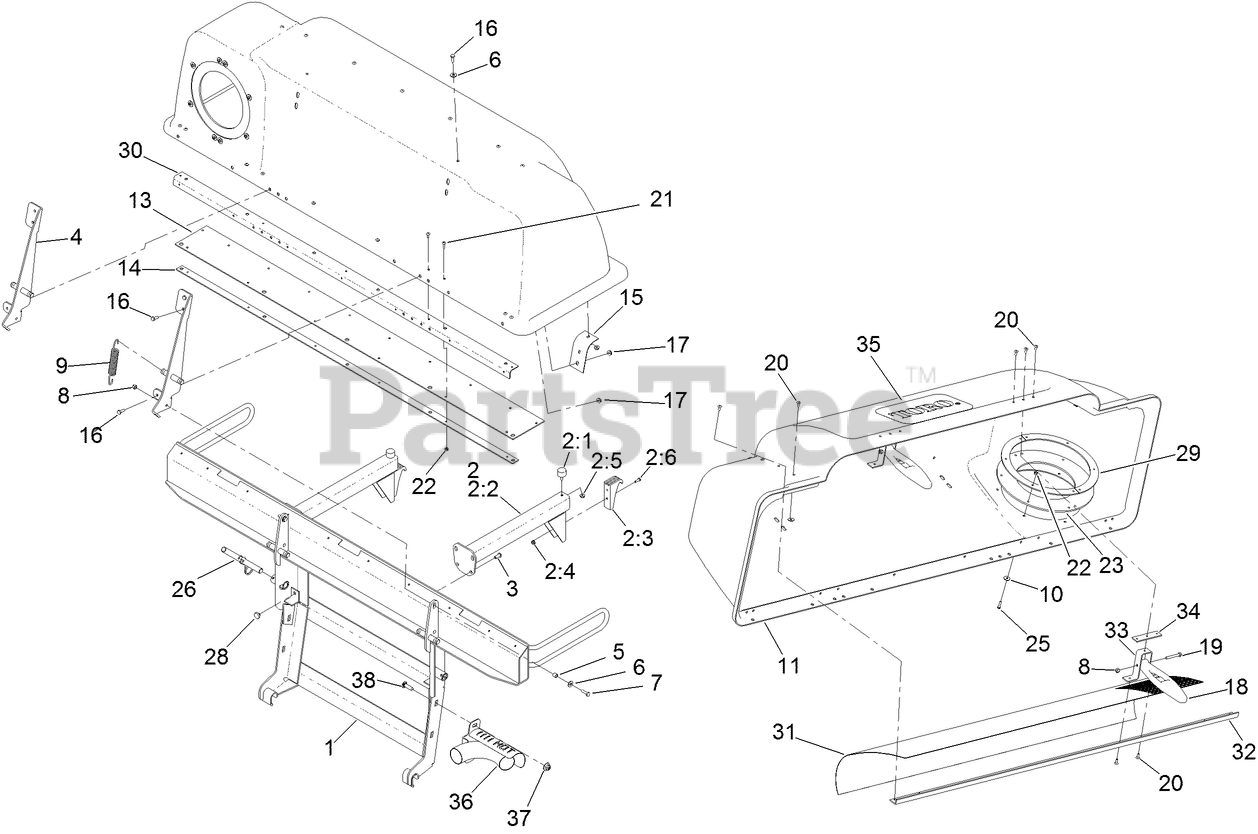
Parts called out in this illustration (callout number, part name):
1	FRAME-TRIPLE BAGGER
2	BAG SUPPORT ASM
2:1	BUMPER
2:2	SUPPORT-BAG
2:4	NUT-HF
2:5	NUT-HF
2:6	SCREW-PPH
3	SCREW-HSBH
5	SPACER
6	WASHER-FLAT
7	SCREW-HH
8	NUT-LOCK, NI
9	SPRING-EXTENSION
10	WASHER-FLAT
11	HOOD ASM
13	SEAL-HINGE
14	PLATE-BACKING
15	REINFORCEMENT-HOOD, BAGGER
16	SCREW-HH
17	NUT-HF
19	SCREW-HH
20	RIVET-BLIND
21	SCREW-HEAD, TRUSS
22	NUT-LOCK, NI
23	SEAL-TUBE
25	SCREW-PPH
26	PIN-MOUNT, BAGGER
28	BUMPER
29	CLAMP-SEAL
30	STIFFENER-BAGGER, TOP
31	SCREEN-BAGGER
32	SUPPORT-SCREEN
33	BRACKET-MOUNT
34	PLATE-LATCH, REINFORCEMENT
35	DECAL
36	EXHAUST DIVERTER ASM
37	NUT-FLANGE, NI
38	SCREW-CARR
